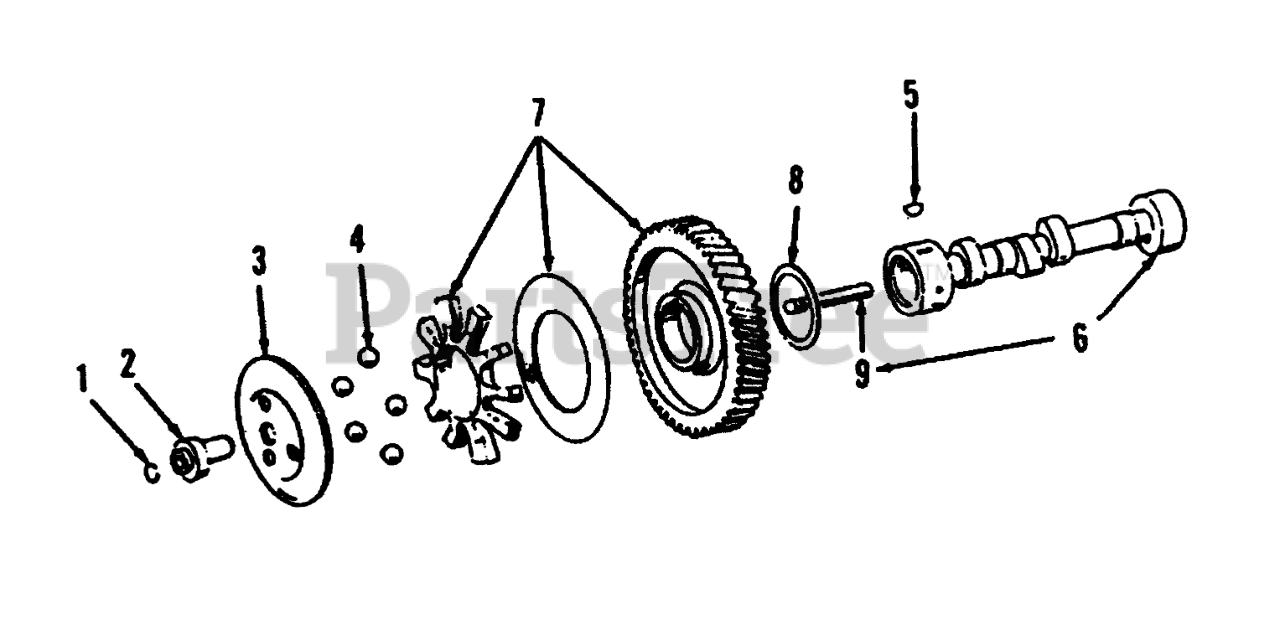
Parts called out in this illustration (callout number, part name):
2	HUB-GOVERNOR CUP
3	CUP-GOVERNOR
4	Ball
6	Camshaft (Includes Center Pin)
8	Washer
9	Pin
